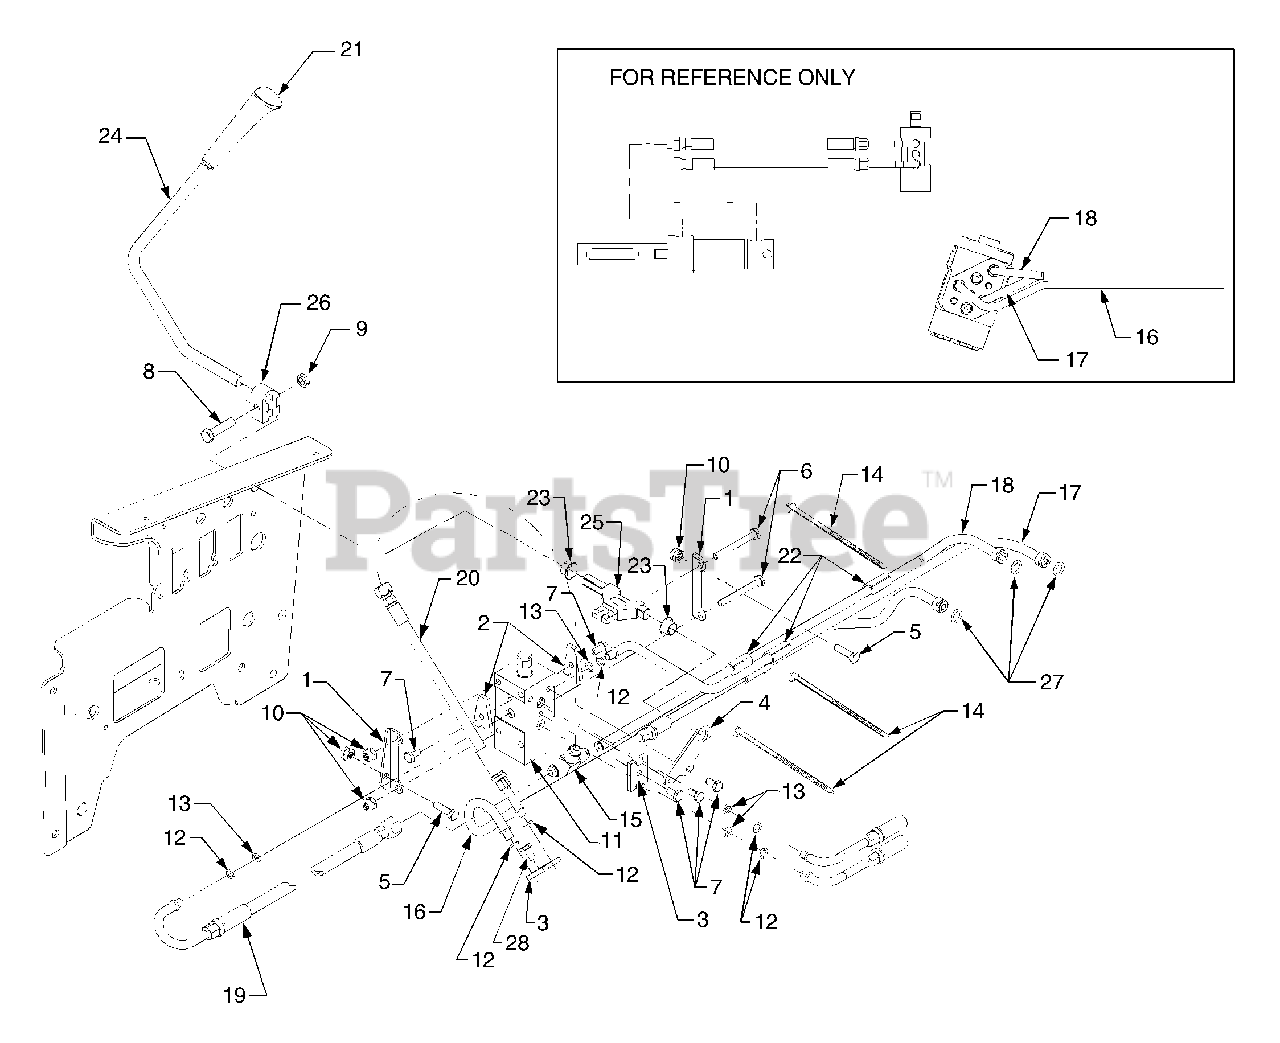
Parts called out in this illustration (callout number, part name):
1	Bracket, Valve Mounting
2	Clamp, Side Valve
3	Clamp, Double Valve
5	Screw, Hex Cap 1/4-20 x 1.0 GR5
6	Screw, Hex Cap 1/4-20 x 2.25 GR5
7	Screw, Hex Cap 1/4-20 x .50 GR5
8	Screw, Hex Cap 5/16-18 x 1.375 GR5
9	Nut, Hex Insert Lock, 5/16-18
10	Nut, Hex Flange Lock, 1/4-20
11	Valve, Hydraulic
12	O-Ring, Backup
13	O-Ring
14	Cable Tie
15	T-Fitting, 9/16-18 Thrd.
16	Tube, Hydraulic (Pump to Strng)
17	Tube, Hydraulic (Aux. from Strng)
18	Tube, Hydraulic (Strng Return)
19	Tube, Hydraulic (Aux Return)
20	Tube, Hydraulic (Return to Pump)
21	Knob, Lift
22	Rubber Spacer
23	Bearing, Nylon Flange
24	Handle, Center Lift Valve
25	Link, Lift
26	Clamp, Handle
27	O-Ring, .426 x .566 x .070
28	Screw, Hex Cap 1/4-20 x .62 GR5
